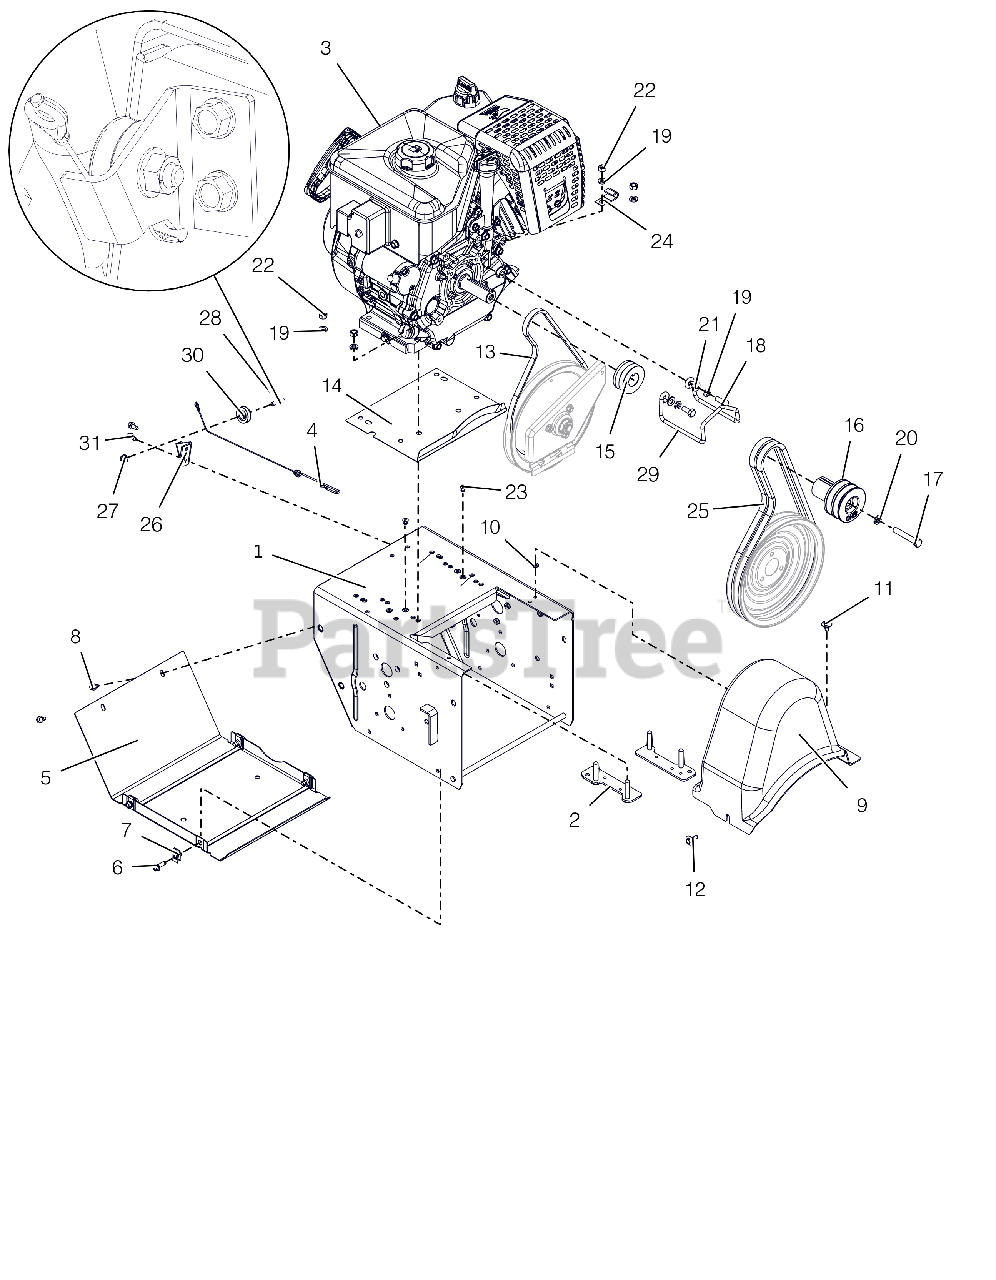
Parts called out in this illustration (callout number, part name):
1	FRAME, MAIN-DELUXE(WELDMENT)
2	STRAP, ENGINE-MEDIUM BLOCK
3	ENGINE, AX306 GEN3 240V60W
4	CABLE, LOWER TRACTION,SS & PRO
5	COVER, BOTTOM
6	BLT-HEX .25-20X.75 HWH YZ GR5
7	NUT-RTNR .25-20X.56
8	SCR-TAP .25-20X.50 HWH TR YWZ
9	COVER, BELT-LARGE
10	NUT-PUSH .25X.50 O.D.
11	SCR-TAP .25-20X.50 LGHWH TR YZ
12	SCR-TAP .25-20X.5 CAPTIVE
13	V-BELT, 3L-WRAPPED
14	BAFFLE, WATER - LARGE BLOCK
15	SHEAVE, DRIVE
16	SHEAVE,ATTACHMENT-SHO 2 GRV
17	BLT-HEX .38-24X2.25 YWZC GR5
18	BLT-HEX .31-24X.75 YWZC GR5
19	WSHR-LK .312X.097 HVY YWZC
20	@WSHR-LK .38X.094 REG YWZC
21	@WSHR-FL-STL.344X.688X.065YWZC
22	@NUT-HEX .31-18 YWZC
23	RVT-POP .187 YZ
24	J-CLAMP
25	V-BELT, HA-RAW EDGE (SET)
26	BRACKET, CABLE PULLEY
27	@NUT-LK-TOP-FLG .25-20 YWZC
28	BOLT, SHLDR-.375X.375X.25-20
29	FINGER, BELT
30	PULLEY, CABLE
31	SCR-TAP .25-20X.50 HWH TR YWZ
